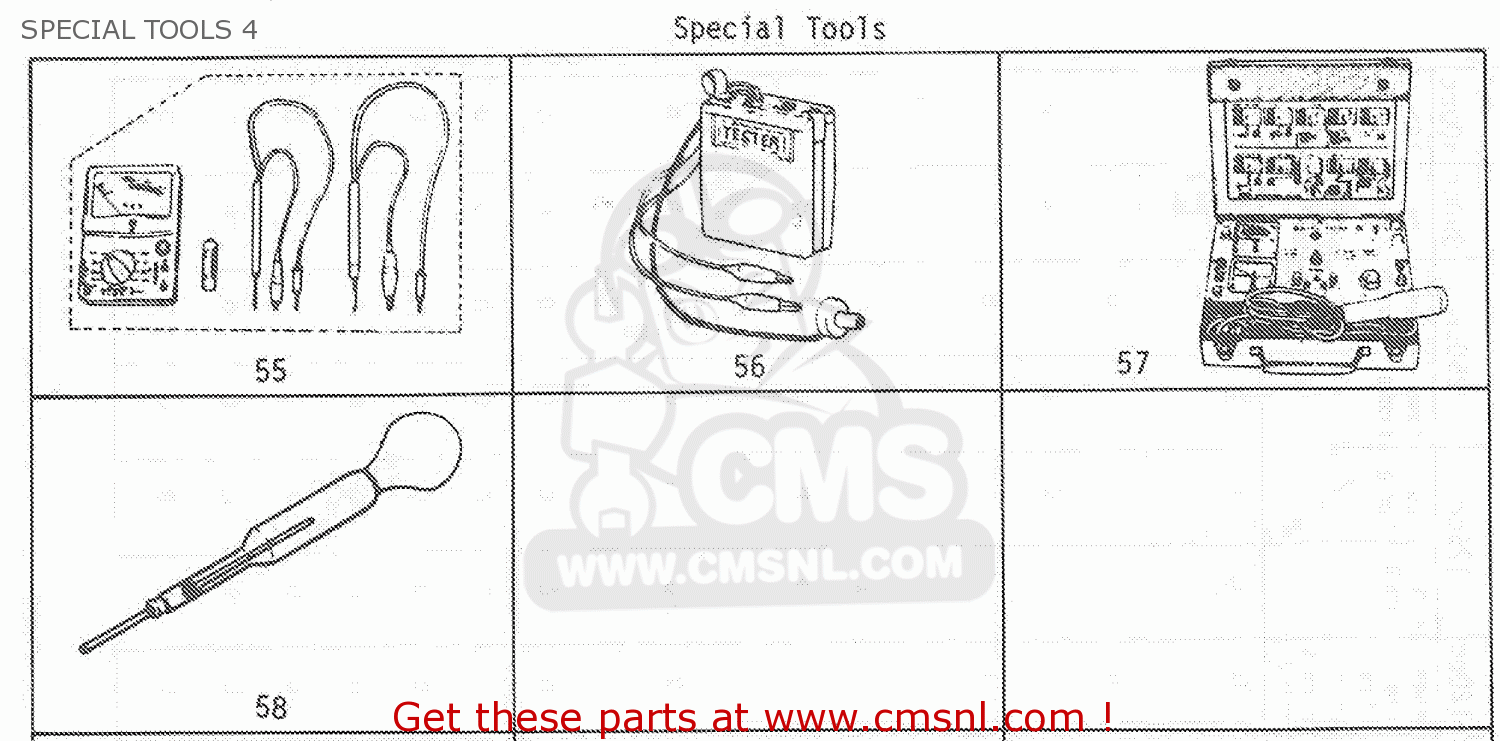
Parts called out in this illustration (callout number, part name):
55	UNIVERSEELMETER
56	TIMING TESTER
57	ELECTRO TESTER
58	HYDROMETER
